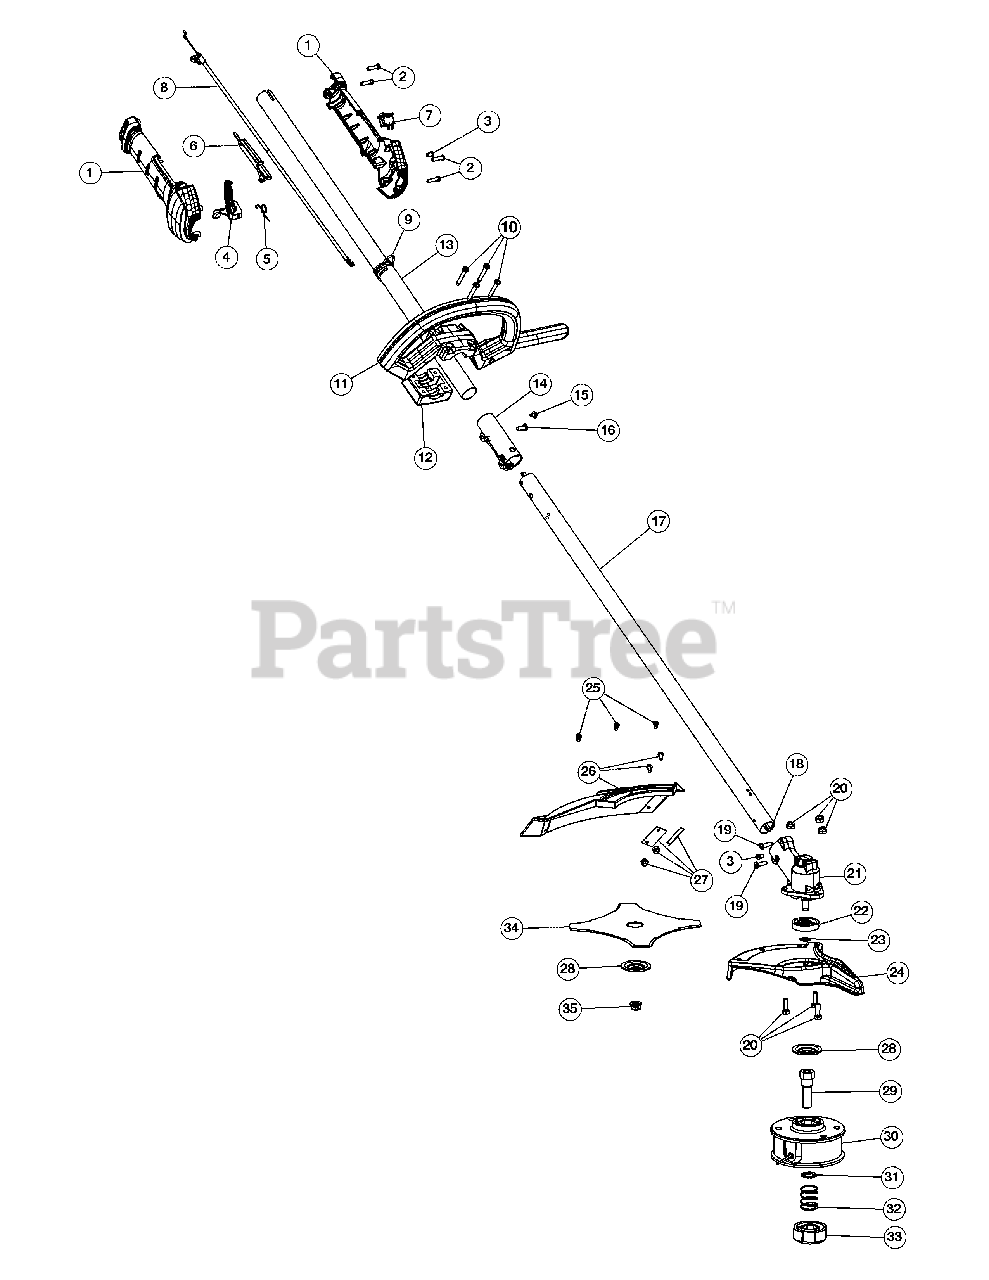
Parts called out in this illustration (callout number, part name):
1	Throttle Grip Assembly (Incl. 2-7)
3	Anti-Rotation Screw
4	Throttle Trigger
5	Throttle Trigger Spring
8	Throttle Cable
9	Harness Clip
11	D-Handle (Incl. 12)
12	D-Handle Base
13	Upper Drive Shaft Assembly
14	Split Boom Coupler Assembly (inludes 15 & 16)
17	Lower Drive Shaft Assembly (Incl. 18)
18	Lower Flex Shaft
19	Gearbox Mounting Hardware
20	Shield Mounting Hardware
21	Gearbox Assembly (Incl. 3, 19 - 20, 22 - 24)
22	Blade Driver
24	Blade Shield/Shield Mount
25	Shield Mounting Screw
26	Shield Assembly (Incl. 27)
27	Blade Assembly
28	Retaining Washer
29	Spool Shaft
30	Outer Spool Assembly
31	Retainer
33	Bump Head Knob Assembly
34	4-Tooth Blade
35	Nut
